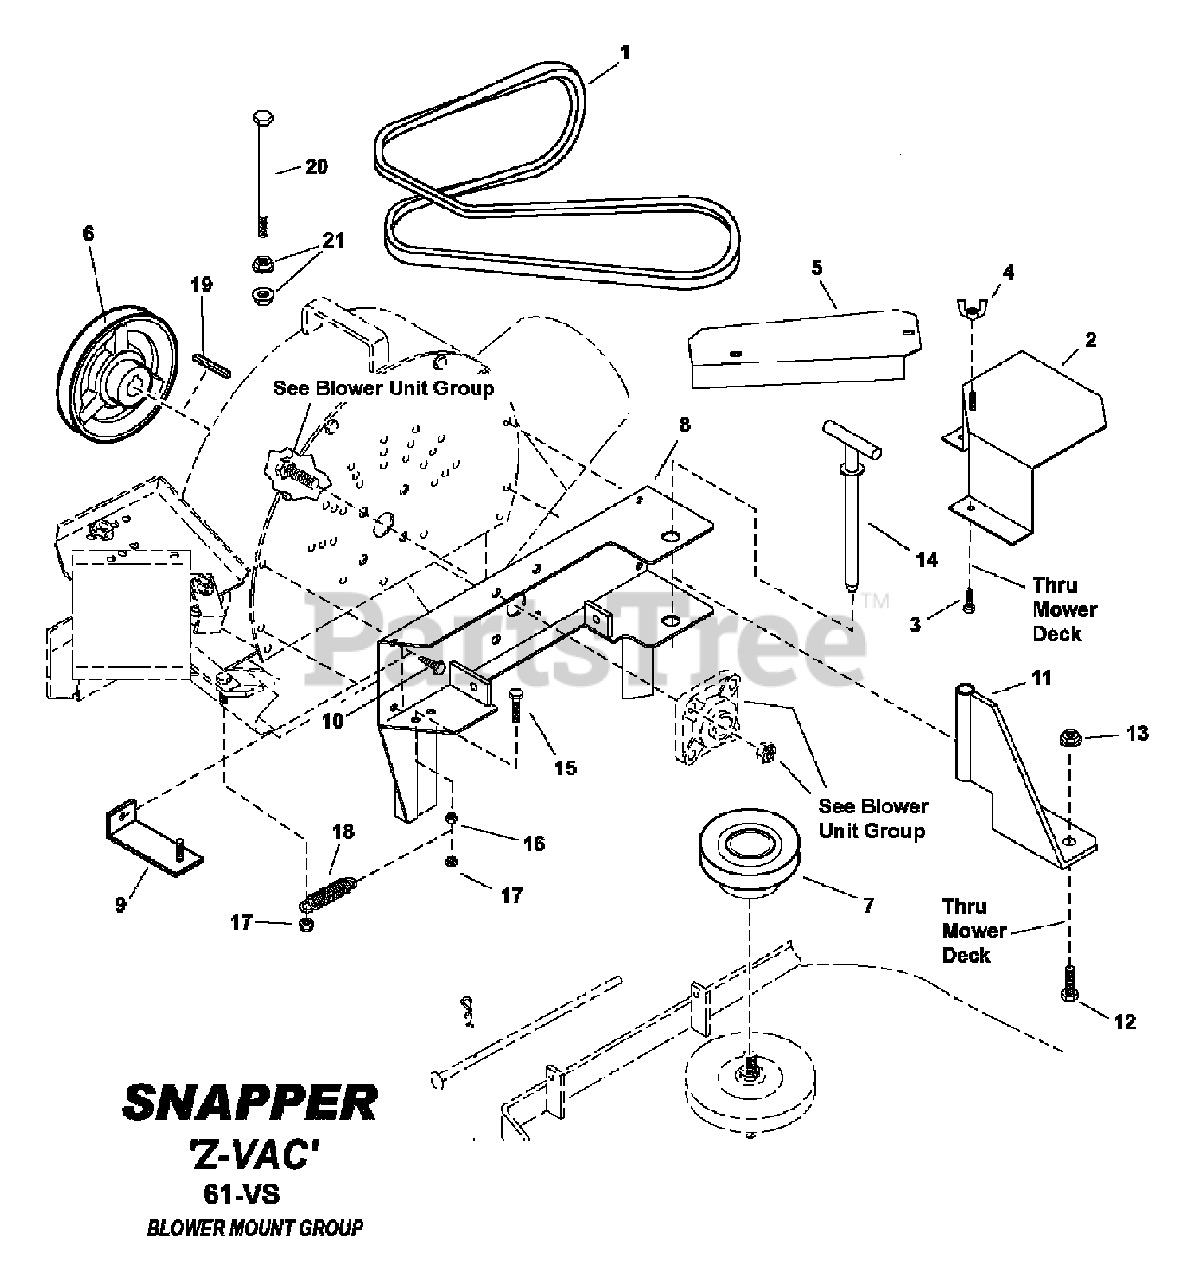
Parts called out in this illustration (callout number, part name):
1	BELT, A Section, 92.0" effective length
2	GUARD, Pulley
3	SCREW, 5/16-18 x 1-1/4" Hex Head Cap, GR5
4	WING LOCKNUT 5/16-18
5	BELT GUARD, 61" Deck
6	PULLEY, Blower Input, 61"
7	PULLEY, 48"/ 52" Spindle
8	WELDMENT, 61" Blower Mount
9	WELDMENT, Guard Support Bracket
10	SCREW, 5/16-18 x 3/4" Hex Washer Self-Tap
11	WELDMENT, Deck Mount Bracket
12	* SCREW, 3/8-16 x 1" Hex Head Cap, GR5
13	NUT, 3/8-16 Hex Flange Lock
14	WELDMENT, T-Handle Pin
15	* SCREW, 5/16-18 x 1" Hex Head Cap, GR5
16	NUT, 5/16-18 Hex Flange Lock
17	NUT, 5/16-18 Hex Center Lock, GR B
18	SPRING, Idler, Fast Vac
19	KEY, 1/4 Square x 1.44
20	SCREW, 3/8-16 x 6" Hex Head Cap, GR5
21	* NUT, 5/16-18 Hex Large Flange Center Lock
